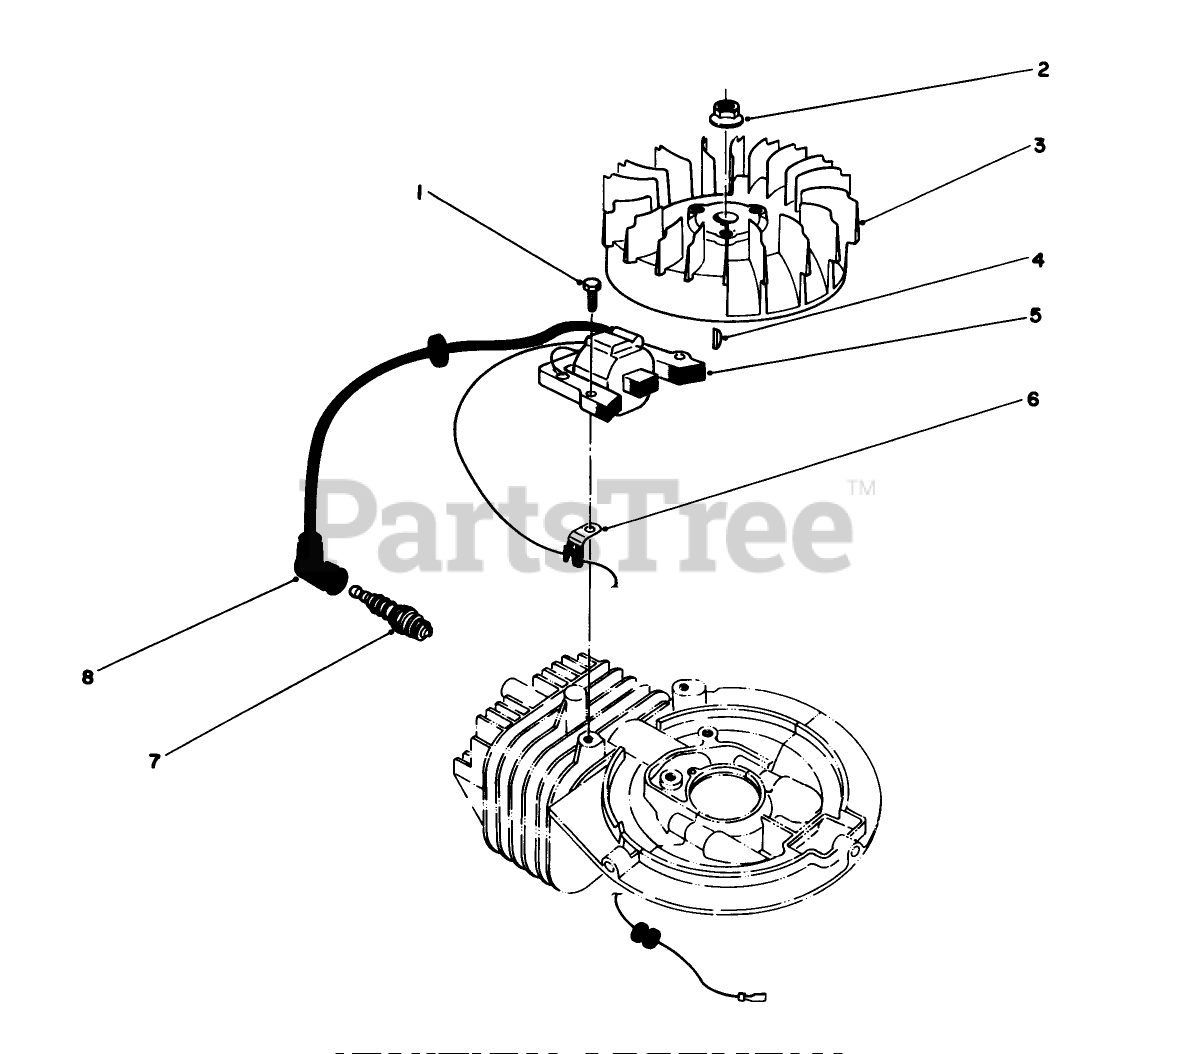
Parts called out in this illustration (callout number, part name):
1	SCREW
3	FLYWHEEL
5	COIL-MAGNETO
6	CLAMP
7	SPARK PLUG
8	CAP-SPARKPLUG
